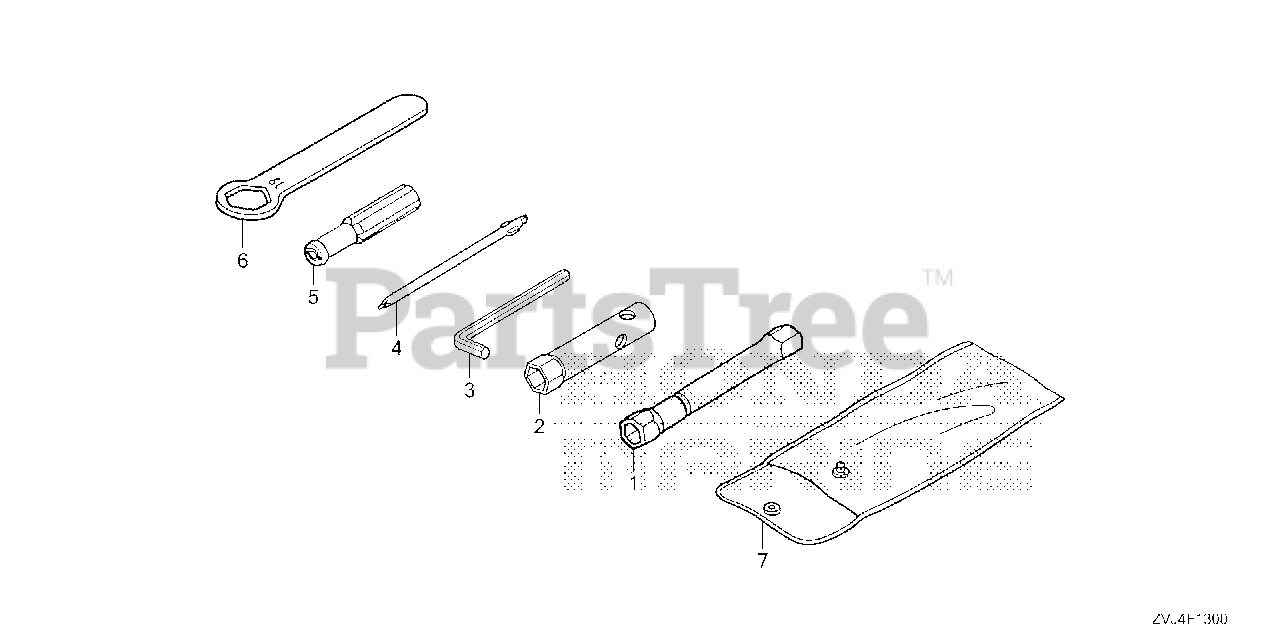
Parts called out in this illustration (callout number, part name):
1	WRENCH, PLUG
2	WRENCH, BOX (10MM)
3	WRENCH, HEX. (6MM)
4	DRIVER 1, PLUS SCREW (NO.2)
5	GRIP, SCREW DRIVER
6	WRENCH, EYE (19MM)
